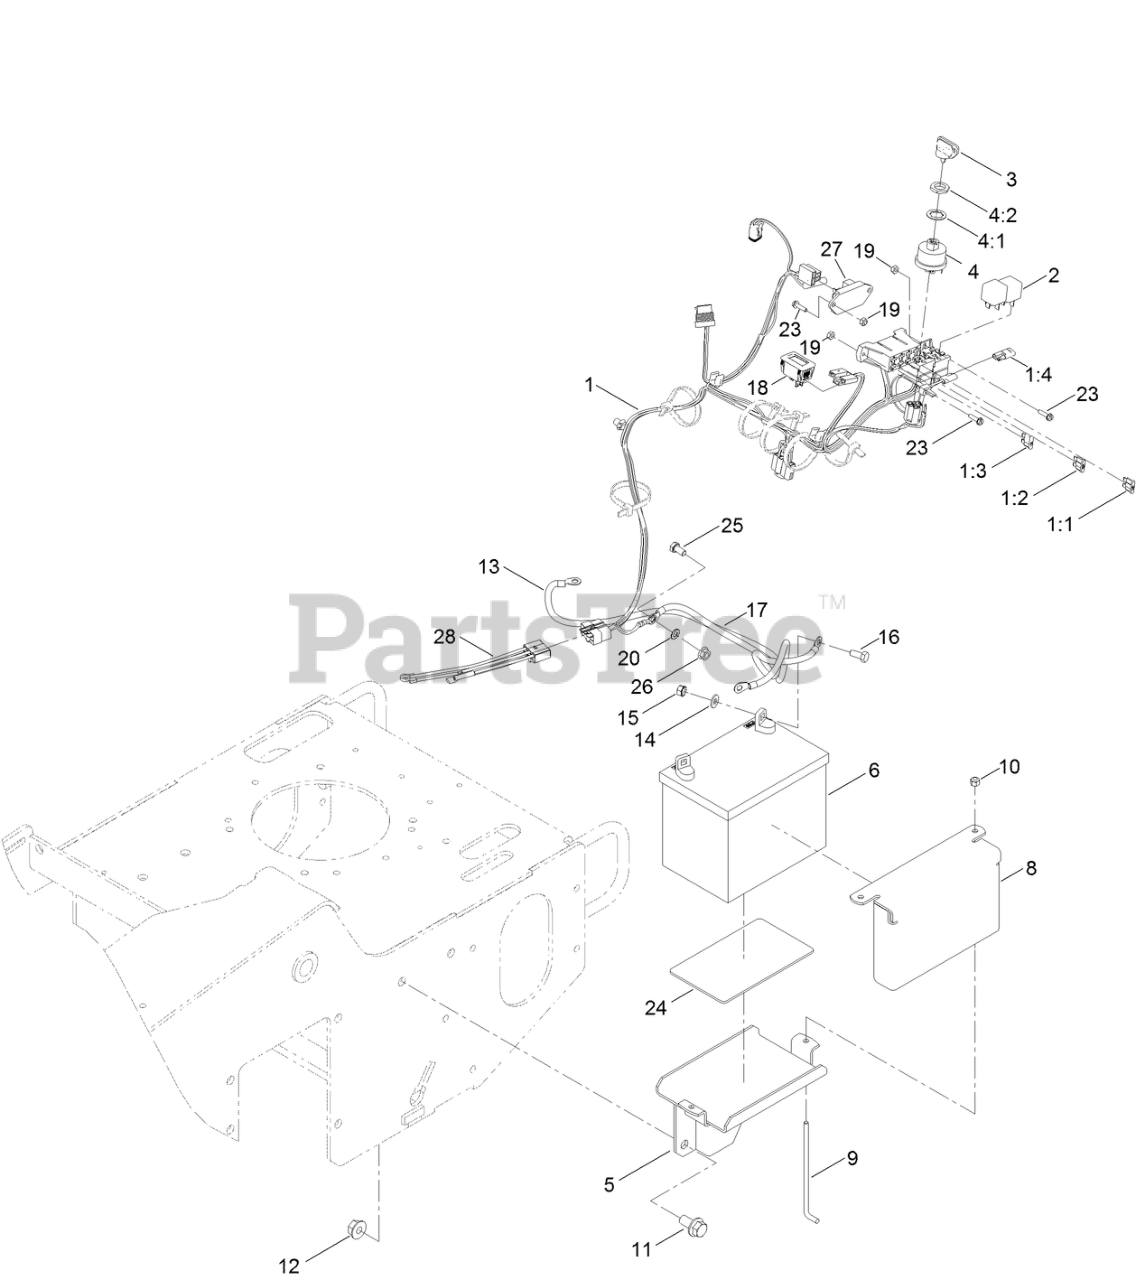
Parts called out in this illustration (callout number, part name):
1	HARNESS-WIRE
1:1	FUSE-BLADE, 30 AMP
1:2	FUSE-BLADE, 25 AMP
1:3	FUSE-BLADE, 20 AMP
1:4	CAP-PLUG
2	RELAY
3	KEY-IGNITION
4:1	WASHER-LOCK
4:2	NUT-HH
5	TRAY-BATTERY
6	BATTERY-DRY
8	PLATE-HOLD DOWN, BATTERY
9	HOLDOWN-BATTERY
10	NUT-LOCK, NI
11	SCREW-HHF
12	NUT-HHF
13	CABLE-BATTERY, POSITIVE
14	WASHER-FLAT
15	NUT-KEPS
16	SCREW-HH
17	CABLE-BATTERY, BLACK
18	HOURMETER
19	NUT-LOCK, NI
20	WASHER-LOCK
23	SCREW-HWH
24	PAD-SKID, ANTI
25	SCREW-HH
26	NUT-HF
27	MODULE-DELAY
28	HARNESS
